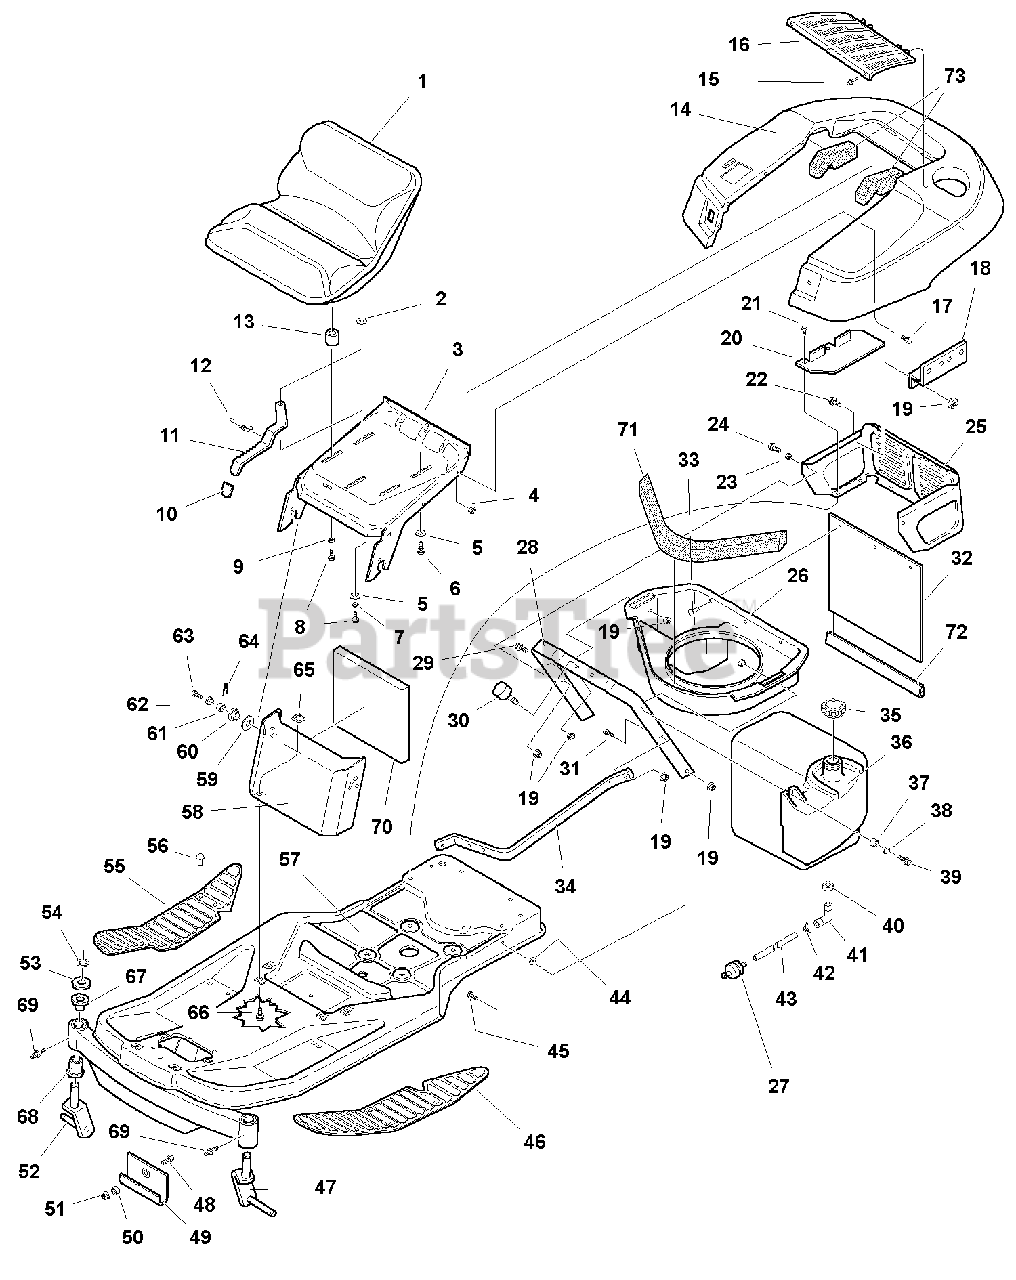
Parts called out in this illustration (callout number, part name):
1	SEAT, High Back, Replacement (**See Footnote)
3	SUPPORT, Seat
4	NUT, Hex Flange Lock, 1/4-20
5	WASHER, Plain
6	CAPSCREW, Hex Lock, 5/16-18 x 3/4
7	LOCKWASHER, 5/16
8	CAPSCREW, Hex, 5/16-18 x 1-1/4
9	NUT, Hex, 5/16-18
11	ADJUSTER, Seat
13	SPACER, Seat Slide
14	DECK, Seat (Orange)
14	DECK, Seat (Red)
16	SCREEN
17	CAPSCREW, Hex Flange Lock, 1/4-20 x 5/8
18	SUPPORT, Reservoirs
19	NUT, Hex Flange Lock, 5/16-18
20	PLATE, Battery
21	CAPSCREW, Taptite, 1/4-20 x 1/2
22	CAPSCREW, Hex Head, 5/16-18 x 5/8
24	CAPSCREW, Hex Head, 5/16-18 x 1-3/4
25	SHROUD, Rear
26	PLENUM, Air Inlet
27	FILTER, Fuel
28	SUPPORT, Seat Deck
29	CAPSCREW, Hex Head, 1/4-20 x 3/4
31	CAPSCREW, Hex Head, 5/16-18 x 1
32	PANEL, Air Duct
34	STRAP, Fuel Tank, Brace
35	CAP, Fuel Tank
38	WASHER
39	CAPSCREW, Taptite, 5/16-18 x 1-1/2
40	BUSHING, Rubber
41	FITTING, Elbow
42	CLAMP, Hose
43	HOSE, 1/4, cut to13" long
44	NUT, Push Pal, 5/16
45	CAPSCREW, Hex Flange Whiz Lock, 5/16-18 x 3/4
46	FOOTREST PAD, LH
47	SPINDLE ASSEMBLY, LH
48	CAPSCREW, Hex Head, 1/2-13 x 1-1/2
49	HOOK, Mower
51	NUT, Flange Lock, 1/2-13
52	SPINDLE ASSEMBLY, RH
53	WASHER
54	E-RING Retainer
55	FOOTREST PAD, RH
56	FASTENER, Panel
57	FRAME ASSEMBLY
58	PANEL, Front
59	WASHER, Plain
60	SPACER, Hood, Plastic
62	PIVOT, Hood
63	CAPSCREW, Taptite, 5/16-18 x 1
65	NUT, Pal, 5/16-18
66	CAPSCREW, Hex Flange Whiz Lock, 5/16-18 x 3/4
67	BUSHING, Upper
68	BEARING, Lower
69	FITTING, Grease
70	INSULATION, Seat Panel
71	SEAL, Air Inlet
73	SEAL, Air Duct
